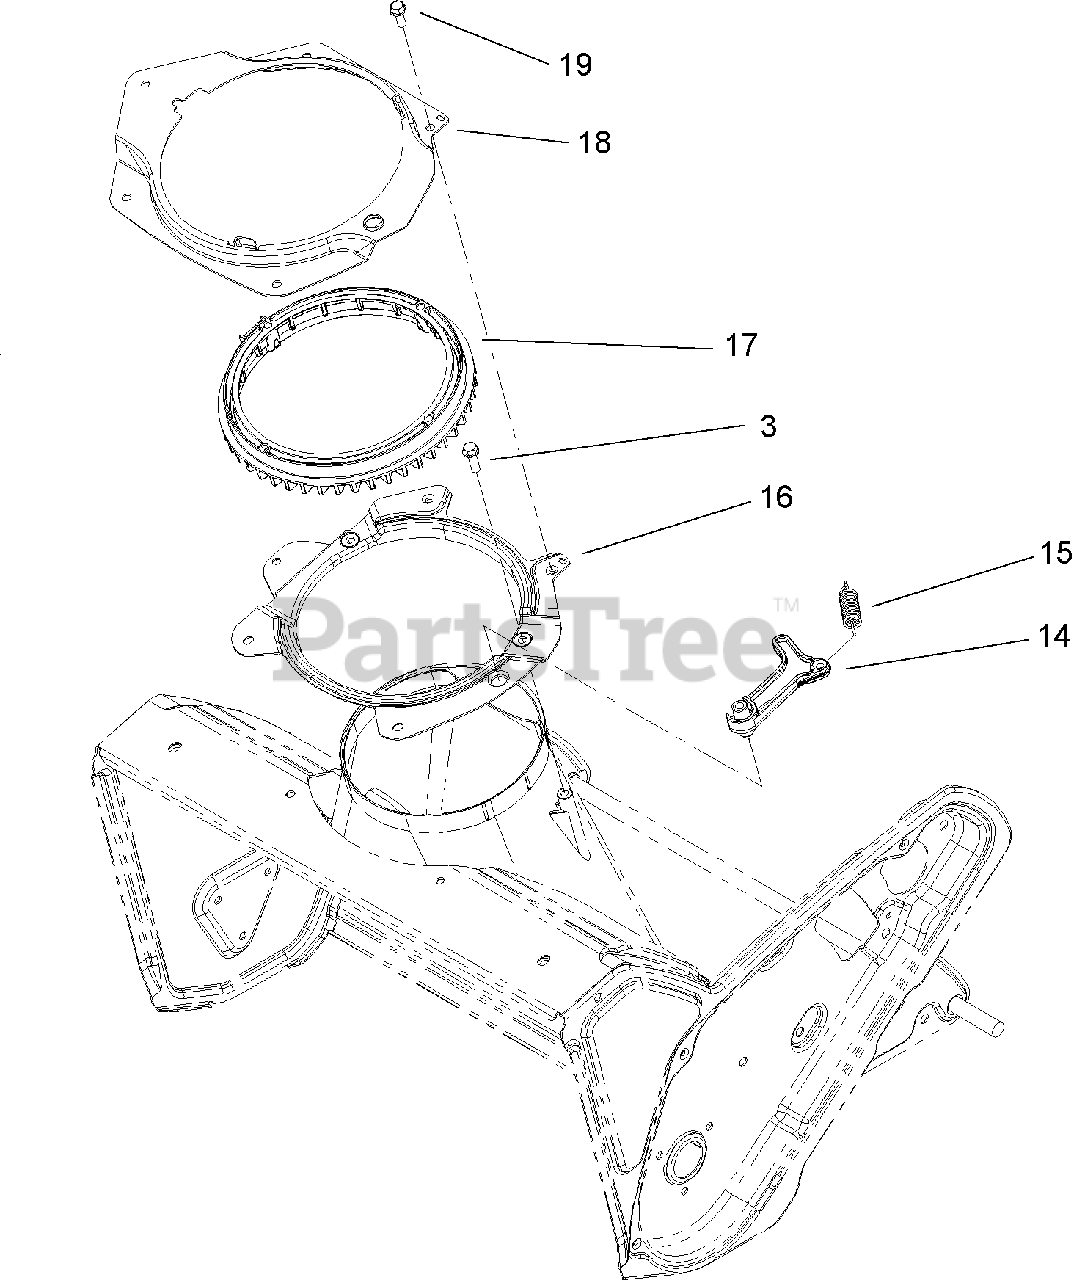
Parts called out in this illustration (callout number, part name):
3	SCREW-HWH
14	PAWL-DETENT
15	SPRING-EXTENSION
16	RING-SUPPORT, CHUTE
17	RING-CHUTE, DETENT
18	RETAINER-RING, CHUTE
19	SCREW-HWH
